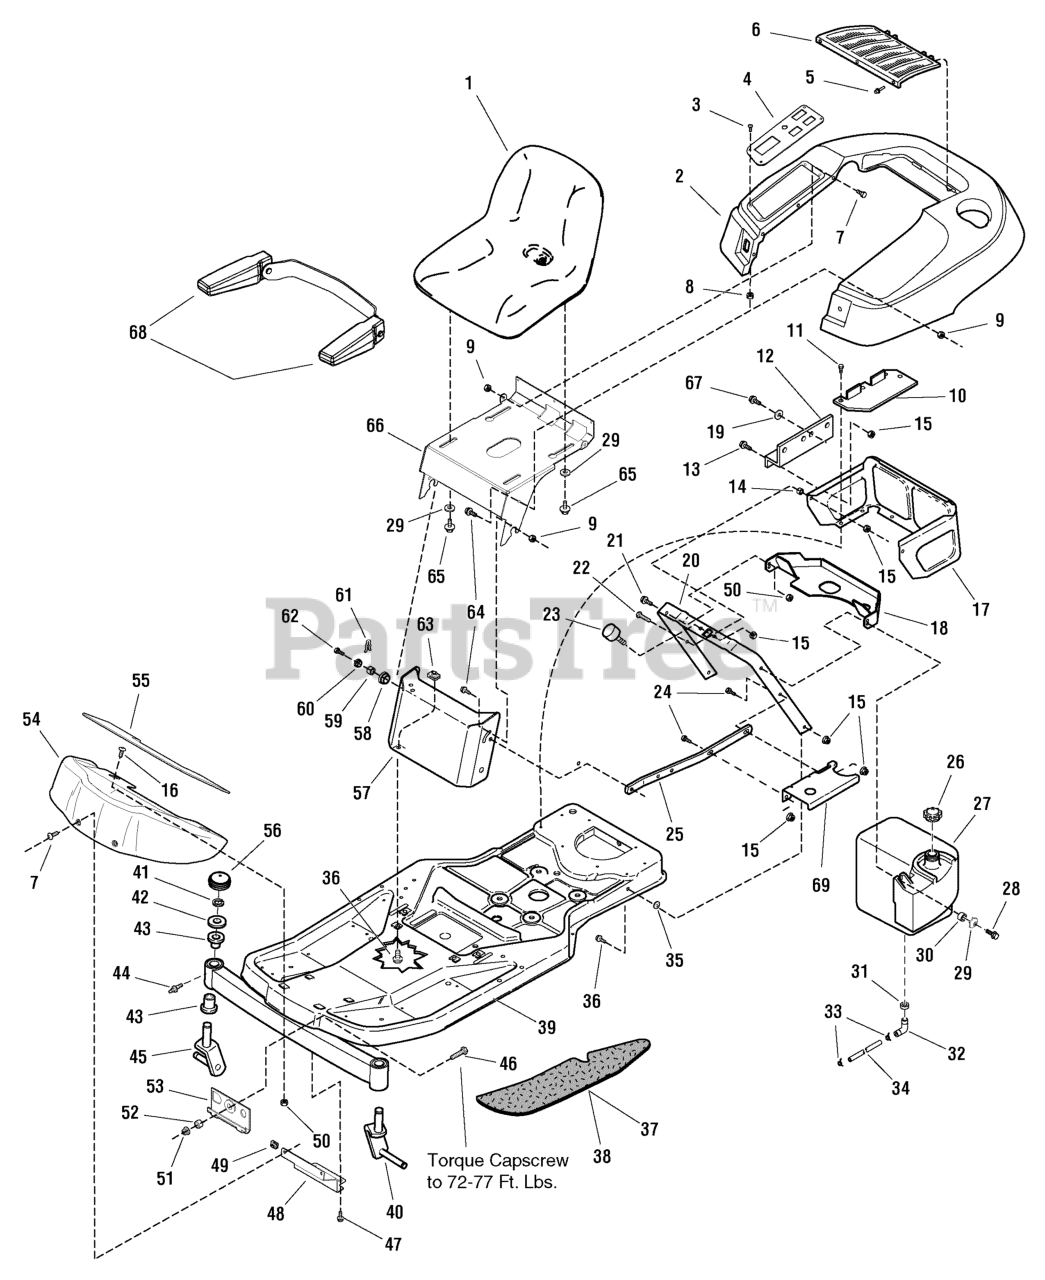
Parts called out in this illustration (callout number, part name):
1	SEAT ASSEMBLY, wthout Arm Rests
2	DECK, Seat
3	CAPSCREW, Hex, Socket Head, 1/4-20 x 7/8, G5
4	PLATE, Pod Control
5	RIVET, Pop
6	SCREEN, Seat Deck
7	SCREW, Truss Head Torx Drive, 1/4-20 x 3/4,
8	NUT, Hex Lock ESNA Light, 1/4-20
9	NUT, Hex Flange ESNA, 1/4-20
10	PLATE, Battery
11	CAPSCREW, Hex Washer Head Taptite, 1/4-20 x 1/2, G5
12	SUPPORT, Reservoirs
13	CAPSCREW, Hex Head, 5/16-18 x 5/8, G5
14	SPACER, Powdered Metal
15	NUT, Hex Flange Whiz Lock, 5/16-18
16	CARRIAGE BOLT, 1/4-20 x 3/4
17	SHROUD, Rear
18	DUCT, Air Inlet
19	WASHER, Plain
20	SUPPORT, Seat Deck
21	CAPSCREW, Hex Head, 1/4-20 x 3/4, G5
22	SCREW, Hex Head Cap, 5/16-18 x 1 3/4
23	BUMPER, Rubber
24	CAPSCREW, Hex Head, 5/16-18 x 1 1/4
25	BRACE, Tank
26	CAP, Fuel Tank
27	TANK, Fuel
28	CAPSCREW, Hex Washer Head Taptite, 5/16-18 x 1-1/2
29	WASHER, Plain
31	BUSHING, Fuel Tank
32	ELBOW, with Screen, Gas Tank To Fuel Line
33	CLAMP, Hose, Wire Type E
34	HOSE, Fuel
35	NUT, Push
36	CAPSCREW, Hex Flange Whiz Lock, 5/16-18 x 3/4
37	PAD, Footrest, R.H.
38	PAD, Footrest, L.H.
39	FRAME & SPINDLES ASSEMBLY, (Includes Ref. Nos. 40, 41, 42, 43, 44 & 45)
40	ARM, Caster, L.H.
41	RING, E-Retaining
42	WASHER, 1
44	FITTING, Lube
45	ARM, Caster, R.H.
46	CAPSCREW, Hex, 1/2-13 x 1-1/2
47	SCREW, Hex Washer Head Taptite, 5/16-18 x 3/4
48	BRACKET, Footrest Support
49	LUG NUT, Speed, 1/4-20
50	NUT, Hex Flange Whiz Lock, 1/4-20
51	NUT, Hex Flange, Two-Way Lock, 1/2-13
53	HOOK & WASHER ASSEMBLY
54	PANEL, Footrest
55	PAD, Footrest, Front
56	CAP, Hub
57	PANEL, Front
60	PIVOT, Hood
61	PIN, Quick
62	CAPSCREW, Hex Washer Head Taptite, 5/16-18 x 1
63	NUT, Speed, Lug Type, 5/16-18
64	SCREW, Hex Flange Whiz Lock, 1/4-20 x 5/8
65	CAPSCREW, Exterior Thread, 5/16-18 x 1
66	SUPPORT, Seat
67	CARRIAGE BOLT, 5/16-18 3/4, G5
68	ARM REST KIT, (L.H. & R.H.)
69	SUPPORT, Fuel Tank
